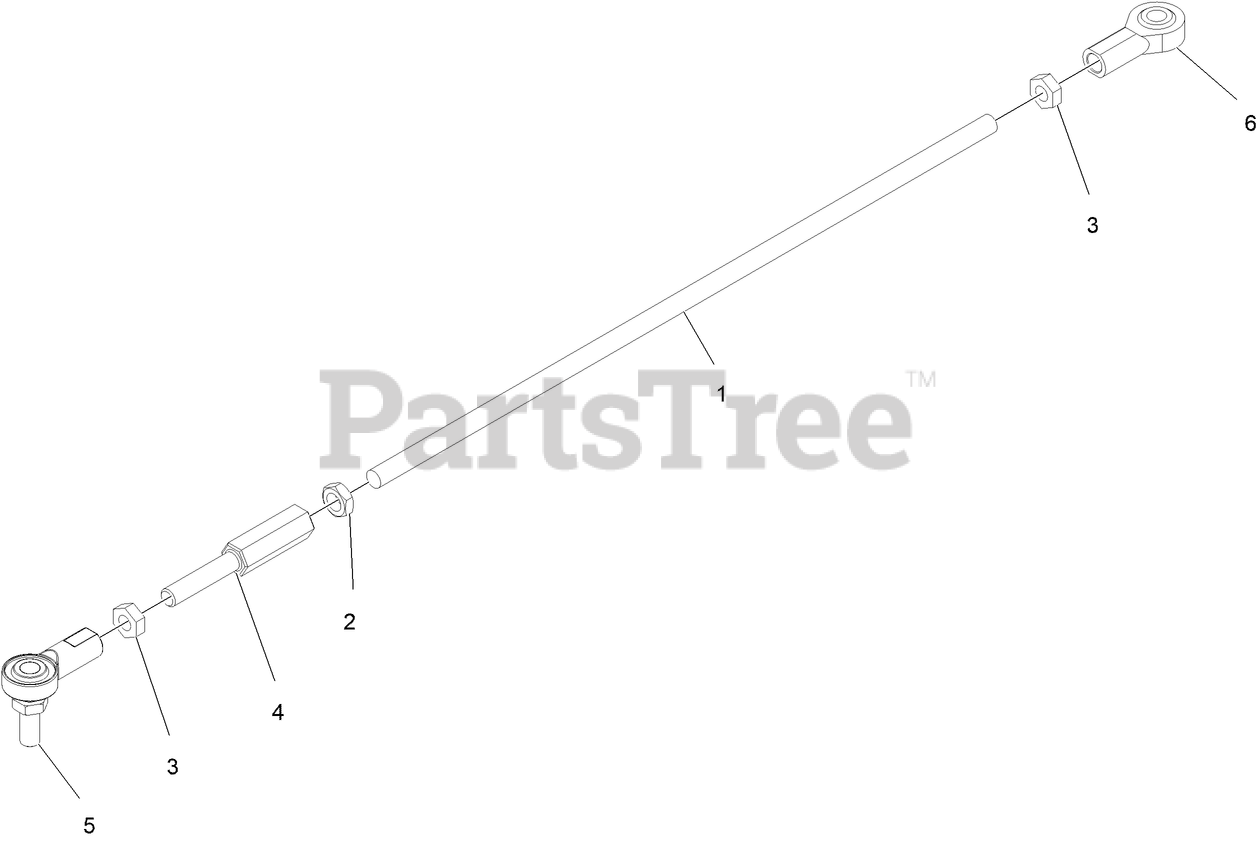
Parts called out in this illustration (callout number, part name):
1	Rod-Motion Control Short
2	NUT-JAM
3	NUT-JAM
4	ROD-ADJUST
5	BALLJOINT
6	BALLJOINT-RH
